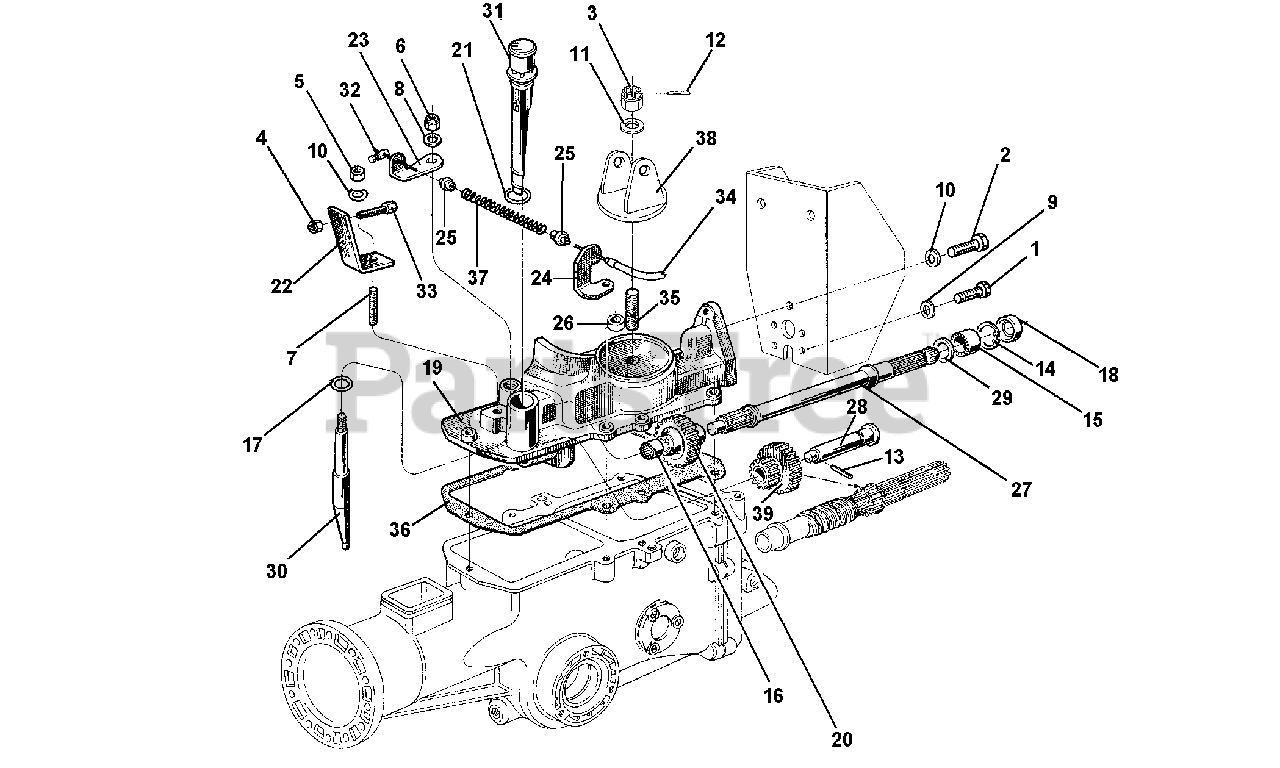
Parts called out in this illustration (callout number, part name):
1	SCREW TE M8 X 30
2	SCREW M10 X 30
3	NUT, HEX INT M12 UNI 5593 6S
6	NUT, SELF LOCKING M8
7	STUD M10 X 37 X 19 X 15 8G
8	WASHER, FLAT 8.4
9	WASHER, LOCK 8.4
10	WASHER, LOCK 10.5
11	WASHER, LOCK 13
12	PIN, LOCKING SW 3 X 22 SPIRAL
13	LOCKING PIN 4 X 24 SPIRAL
15	BALL BEARING
16	ROLLER BEARING
17	O-RING 2056 14.00 X 1.78
19	SYNCHRONIZED P.T.O. COVER
21	RUBBER RING
22	BRACKET CLUTCH CONTRAST
23	LEVER RELEASE
24	LOCK FOR DIFFERENTIAL SHEATH
27	SYNCHRONIZED P.T.O. SHAFT
31	CAP, WITH MEASURING ROD
32	PIN, CABLE CLAMP
33	SCREW, ADJUSTING M8
34	WIRE SHEATH DIFFER. LOCKING
39	DOUBLE GEAR
